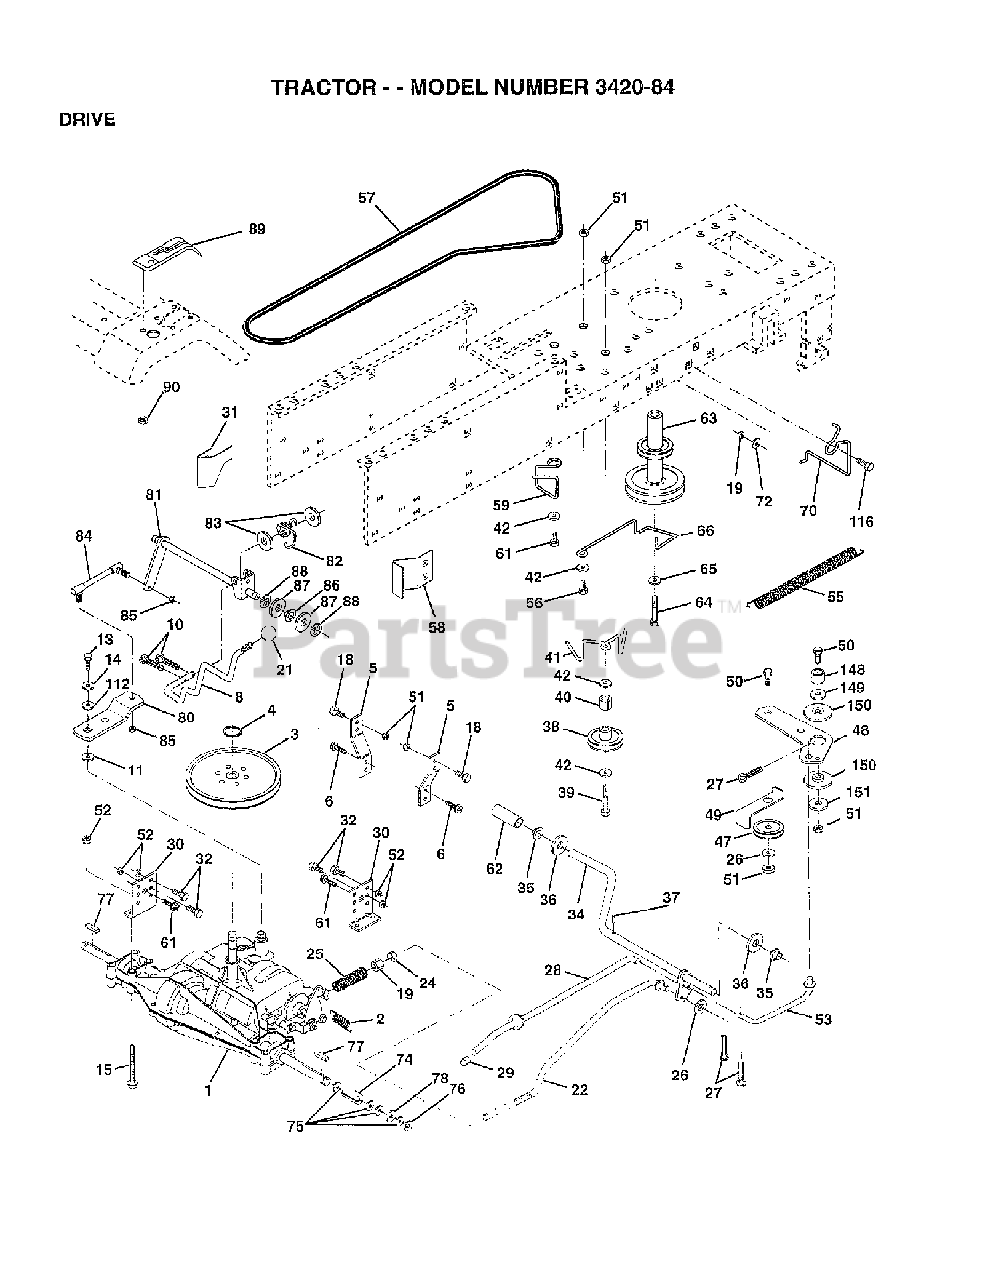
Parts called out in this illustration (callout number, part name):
2	SPRING T
3	PULLEY TRANS
4	RETAINING RING LT
5	STRAP TORQUE
6	Screw, Lt
10	PIN COTTER
11	WASH-SHFT PLT LT
14	LOCKWASHER
15	BOLT HEX 5/16-18 GR 5
19	NUT
21	KNOB T (1/2-HOLE)
22	ROD BRAKE
24	NUT
25	SPRING ROD LT
27	COTTER PIN
29	PLUNGER CAP
30	BRACKET TRANSAXLE
31	KEEPER BELT LH
32	BOLT
34	SHAFT, FOOT PEDAL
35	BEARING.NYLON
36	WASHER LT
37	Drive Pin, 3/16 X 1"
38	FLAT IDLER PULLEY
40	SPACER T
42	WASHER
47	Idler Pulley
48	BELLCRANK, CLUTCH
49	RETAIN BELT
50	Hex Bolt
51	LOCKNUT
52	LOCKNUT
55	SPRING, RETURN LT
62	PEDAL COVER
63	PULLEY ENGINE
65	LOCKWASHER
66	KEEPER BELT ENGINE
70	KEEPER BELT ENG
72	WASHER
74	SPACER LT
76	E-RING LT
77	SQUARE KEY
81	SHAFT ASSY
82	SPRING,TORSION
83	WASHER
84	ROD TIE 20"
85	NUT LOCK CENTER 1/4 -28 FNTHD
87	WASHER D
88	KLIP RING
89	CONSOLE SHIFT
90	NUT.PUSH.3/16
112	WASHER LT
113	STRAP TORQUE LH LT
116	BOLT
121	NYLINER CLUTCHING
148	GUIDE
150	BUSHING NYLON COLLERED
151	WASHER 12/32X2X10GA
